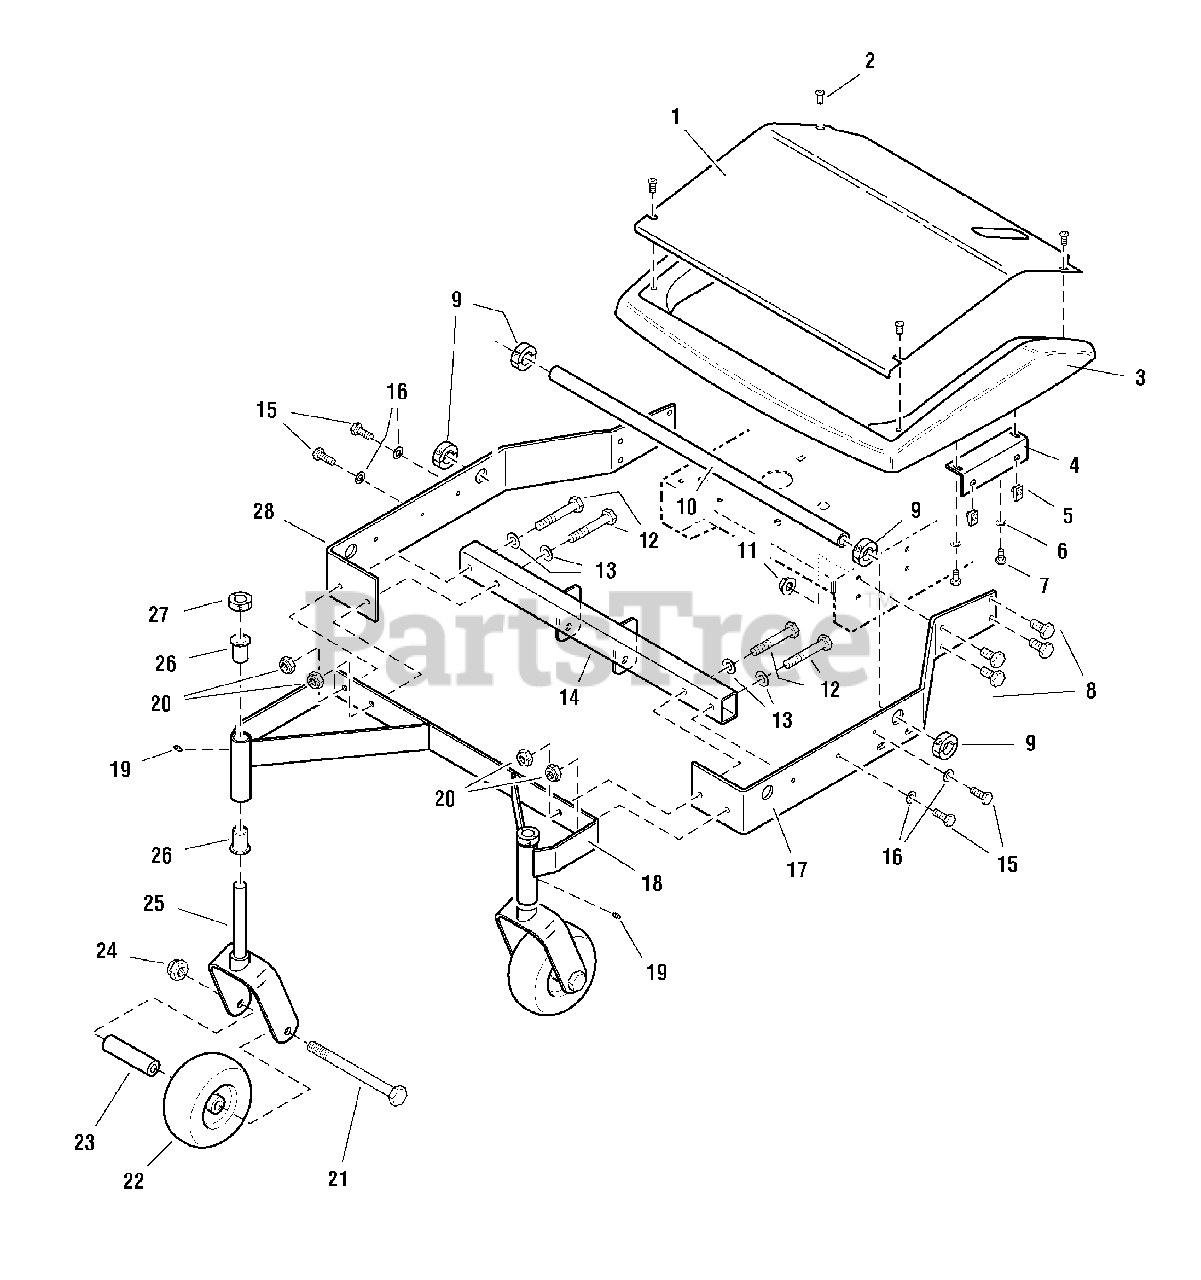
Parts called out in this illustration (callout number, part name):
1	SHIELD INSERT
2	SCREW, Allen Head, 1/4-20 x 1/2
3	GUARD, Mower Deck
4	SHIELD MOUNT BRACKET
5	BODY CLIP, 5/16-18
6	LOCKWASHER, 1/4
7	CAPSCREW, Hex Head, 1/4-20 x 3/4
8	CAPSCREW, Hex Head, 3/8-16 x 1
9	COLLAR, Double Split, 1
11	NUT, Hex Serrated Flange, 3/8-16
12	CAPSCREW, Hex Head, 3/8-16 x 2-1/2
13	WASHER, 3/8
15	BOLT, 1/4-20 X 1", GD
16	WASHER, 5/16
17	FRAME RAIL - LH
18	CASTER MOUNT FRAME
19	GREASE FITTING, 1/4-28
20	NUT, Hex Nylon Lock, 3/8-16
21	CAPSCREW, Hex Head, 1/2-13 x 5-1/2
22	CASTER TIRE
24	NUT, Hex Nylon Lock, 1/2-13
25	CASTER YOKE
26	BUSHING, FLANGE, 3/4 X 1
27	COLLAR, Split, 3/4
28	FRAME RAIL - RH
